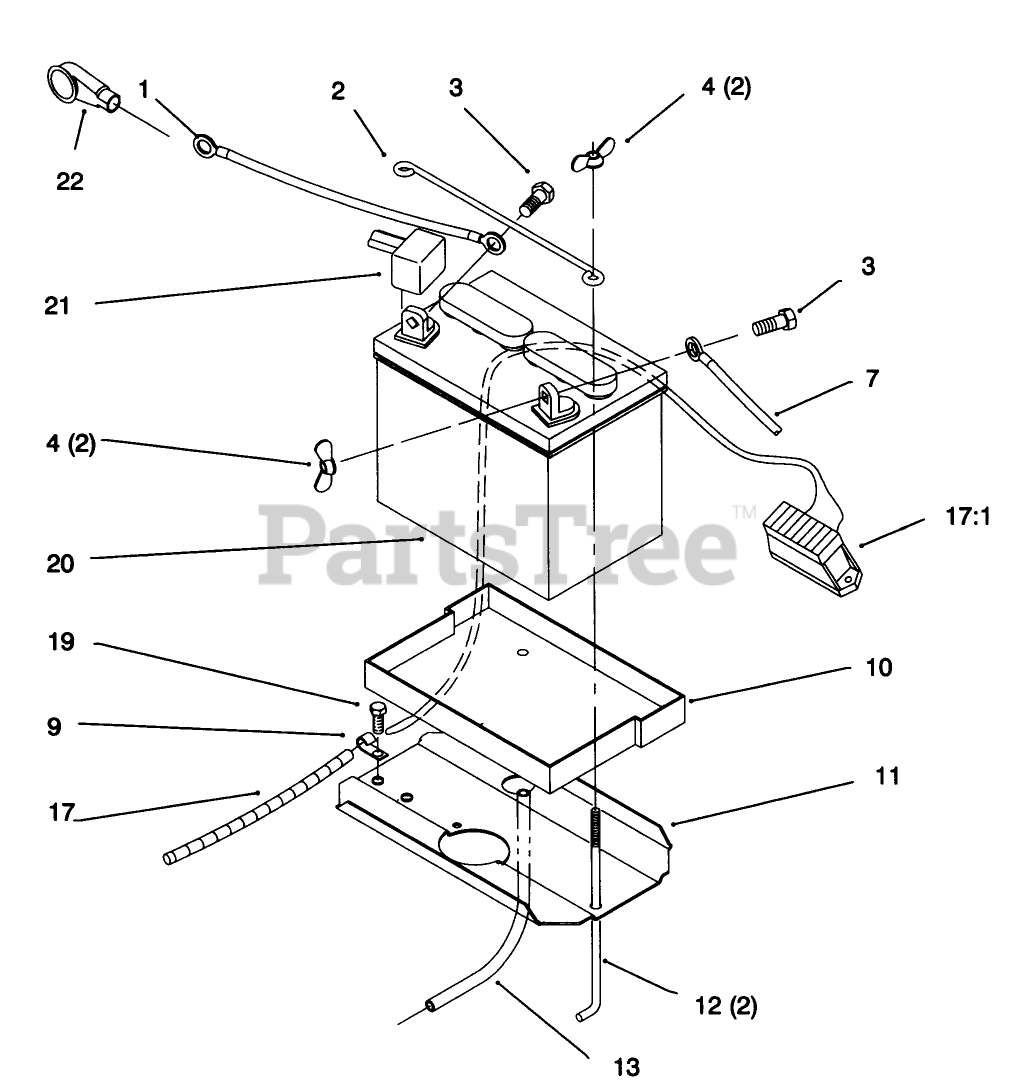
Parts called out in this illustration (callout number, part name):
1	WIRE-21 INCH
1	WIRE -10" RED
2	ROD-BATTERY HOLD DWN
3	SCREW-HH
4	NUT-WING
7	WIRE -BLACK
7	CABLE
9	CLIP
10	TRAY-BATTERY
11	PLATE-BATTERY
13	TUBE-21" BATTERY DRAIN
17	WIRE HARNESS
19	SCREW-HWHTF
22	BOOT-INSULATOR, TERMINAL
